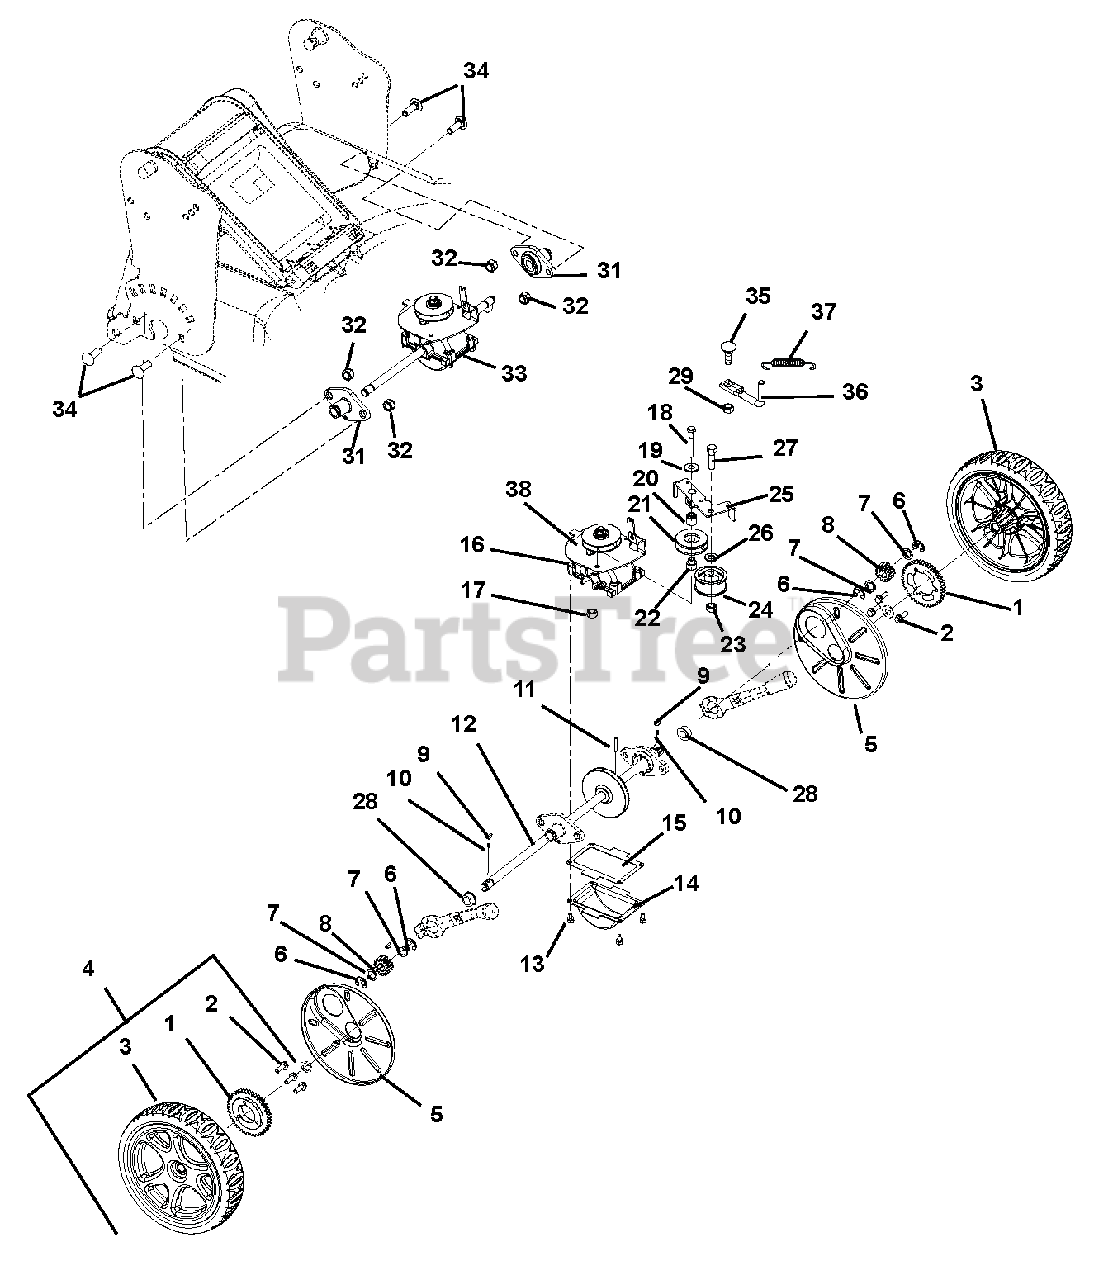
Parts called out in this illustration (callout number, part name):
1	GEAR, WHEEL
2	SCR-TAP .25-15X.75 HI-LO
3	WHEEL, 8.5" WBLM
4	ASSY, LM REAR WHEEL
5	WHEEL COVER
6	RG-RTNG-EXT .500X.042 (E)
7	WASHER, .500X.750X.020 THRUST
8	PINION, WBLM DRIVE
9	KEY-WDRF .125X.50X.20 (HRDEND)
10	SPRING, .134X.180X.144 COMP.
12	SHAFT, TRANSMISSION OUTPUT
13	@SCR-TAP 10-24X.375 HWH YZ TR
14	SUMP, GEARBOX
15	GASKET, TRANSMISSION
16	KIT, WBLM TRANS HOUSING
17	@NUT-LK-TOP-FLG .25-20 YWZC
18	BLT-HEX .25-20X2.25 GR8 YWZC
19	@WSHR-FL-STL.312X.734X.065 YWZ
20	SPACER, IDLER ARM
21	IDLER, 3L FRONT SIDE .38X1.875
22	SPACER, V-IDLER PULLEY
23	@NUT-LK-CTR .38-16 YWZC
24	IDLER - FLAT 1.875OD X .75WIDE
25	ARM, TRANSMISSION IDLER
26	@WSHR-FL-STL.406X.812X.065 YWZ
27	@BLT-HEX .38-16X1.38 GR5 YWZC
28	BUSHING, TRANS OUTPUT SHAFT
29	@NUT-SPNLK-FLG .25-20 YWZC
31	KIT, WHEEL MOUNT HUB SERVICE
32	@NUT-LK-TOP-FLG .31-18 YWZC
33	KIT, BLADE RUNNER TRANS SRVC
34	@BLT-RDHDSQNK .31-18X1.00 G5YZ
35	@BLT-RDHDSQNK .25-20X.50 G5YZ
36	FINGER, BELT
37	SG-TENS .051X.60X2.25 WLD 7.0
38	BRKT, BLADE RUNNER TRANSMISSIO
